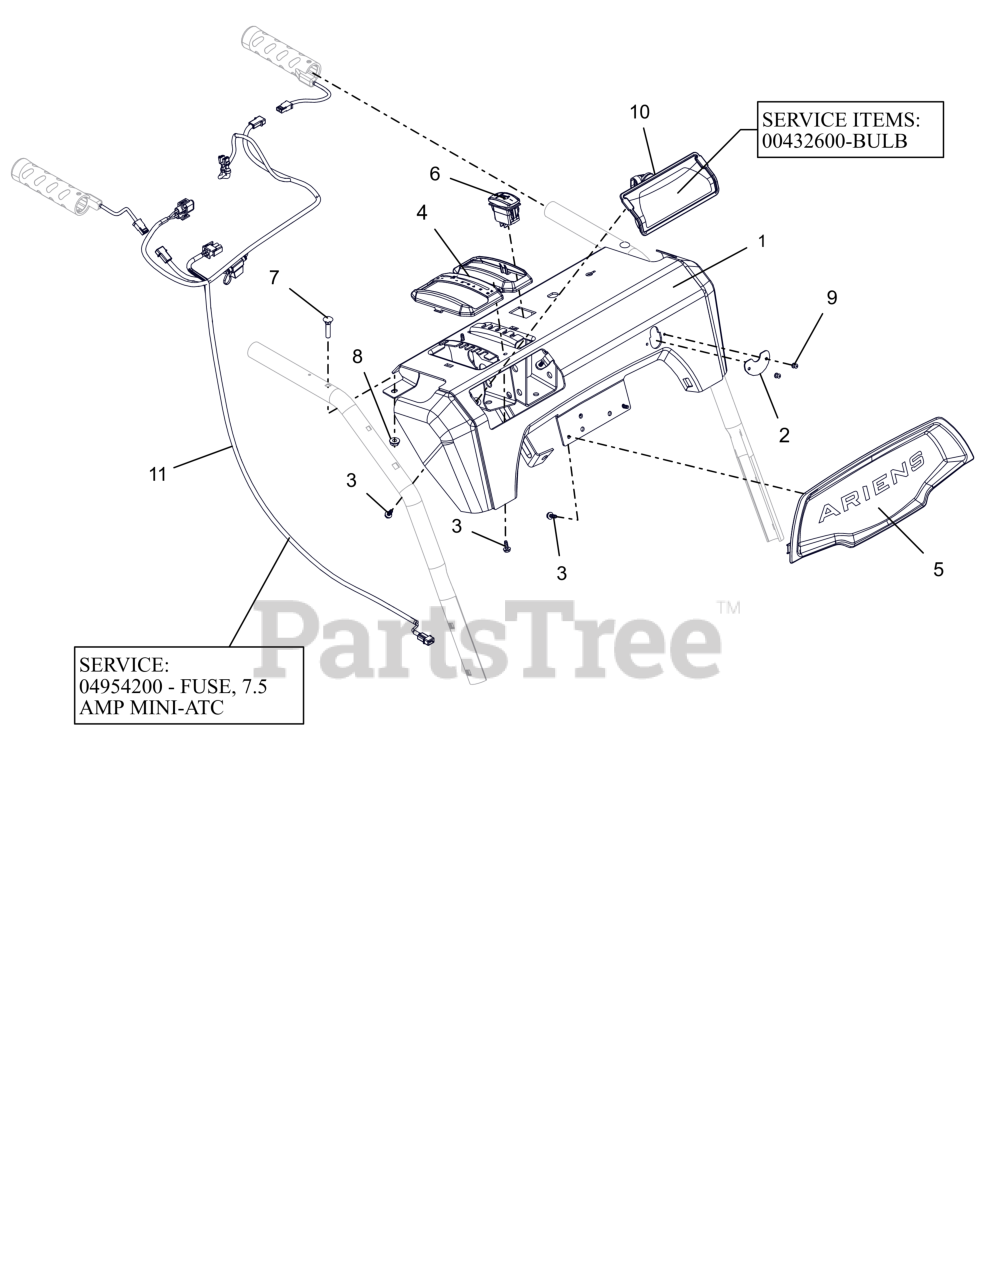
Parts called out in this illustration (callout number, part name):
1	PANEL, CONTROL-EFI ID W/DECAL
2	COVER, DASH BRKT, ID
3	SCR, PLASTIC #10X.50
4	BEZEL, SHIFT - FRICTION SNOW
5	BEZEL, DASH - ARIENS LG DASH
6	SWITCH,ROCKER SPST-ON/OFF
7	BLT-RDHDXLSQNK.25-20X1.25 G5ZC
8	NUT-LK-CTR-FLG .25-20 ZC120
9	RVT-POP #43 .125X.313 STL ZINC
10	HEADLIGHT ASY, HALO 20W 2SHOT
10	BULB, LIGHT-HALOGEN 20W
11	HARNESS,LIGHT&WARMER - EFI
11	FUSE, 7.5 AMP MINI-ATC
